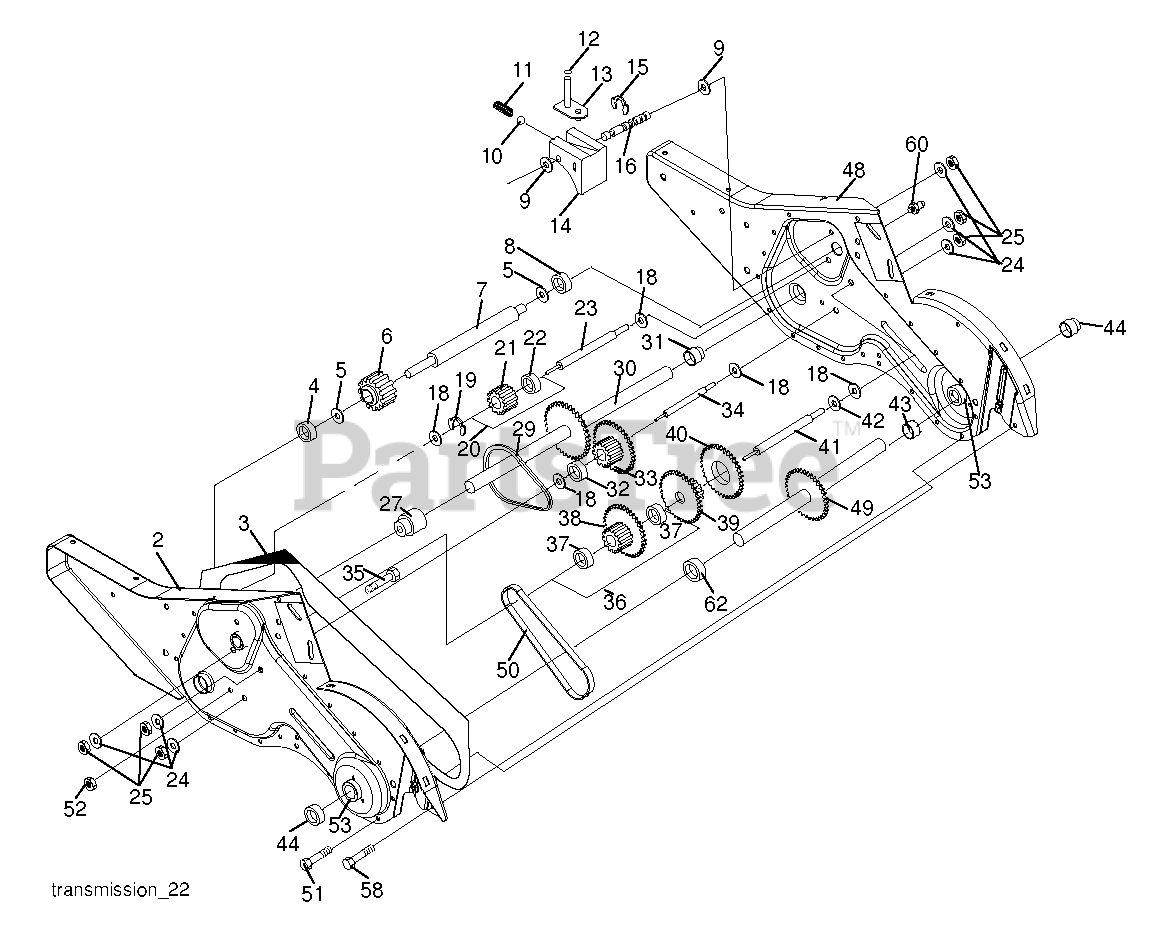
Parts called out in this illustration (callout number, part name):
2	GEARCASE.ASM.CRT.LH.W/BEARING
3	GASKET, GEARCASE
4	NEEDLE BRNG LT
5	THRUST WASHER
6	Pinion Input Gear, CRT Tiller
7	SHAFT.INPUT."D".TILLER
8	BEARING TI
9	WASHER, SEAL
10	STEEL BALL KIT
11	SPRING-SHIFT CRT
12	O-RING TI
13	SHIFTING ARM
14	SHIFT FORK TI
15	KLIP RING
16	SHAFT.SHIFTER.TILLER
19	KLIP RING
20	GEAR ASSY CRT
21	GEAR-REV IDLR CRT
22	NEEDLE BEARING TI
23	SHAFT CRT
24	LOCKWASHER
27	BEARING.GROUND.DRIVE
29	CHAIN CRT
30	GROUND SHAFT ASS'Y
31	BEARING, SHAFT RH CRT
32	SPACER TI
33	SPRCKT 8 GEAR CRT
34	SHAFT.SECONDARY.REDUCTION.CRT
35	SCRW WHIZ LOK CRT
36	SPROCKET ASS'Y W/BRG
37	Needle Bearing, .875 X .687 Oe.50
38	SPROCKET, TINE
39	GEAR TI
41	SHAFT.REDUCTION.TILLER
42	BRNG RACE T
43	SPACER TI
44	SEAL ASM, OIL
48	GEARCASE.ASM.CRT.RH.W/BEARING
49	SHAFT.ASM.TINE
50	CHAIN.TILLER
51	SCREW
53	BEARING.SHAFT.TINE
58	BOLT SHOULDER 1/4-20 UNC X.875
60	FITTING.GREASE.TAPERED
